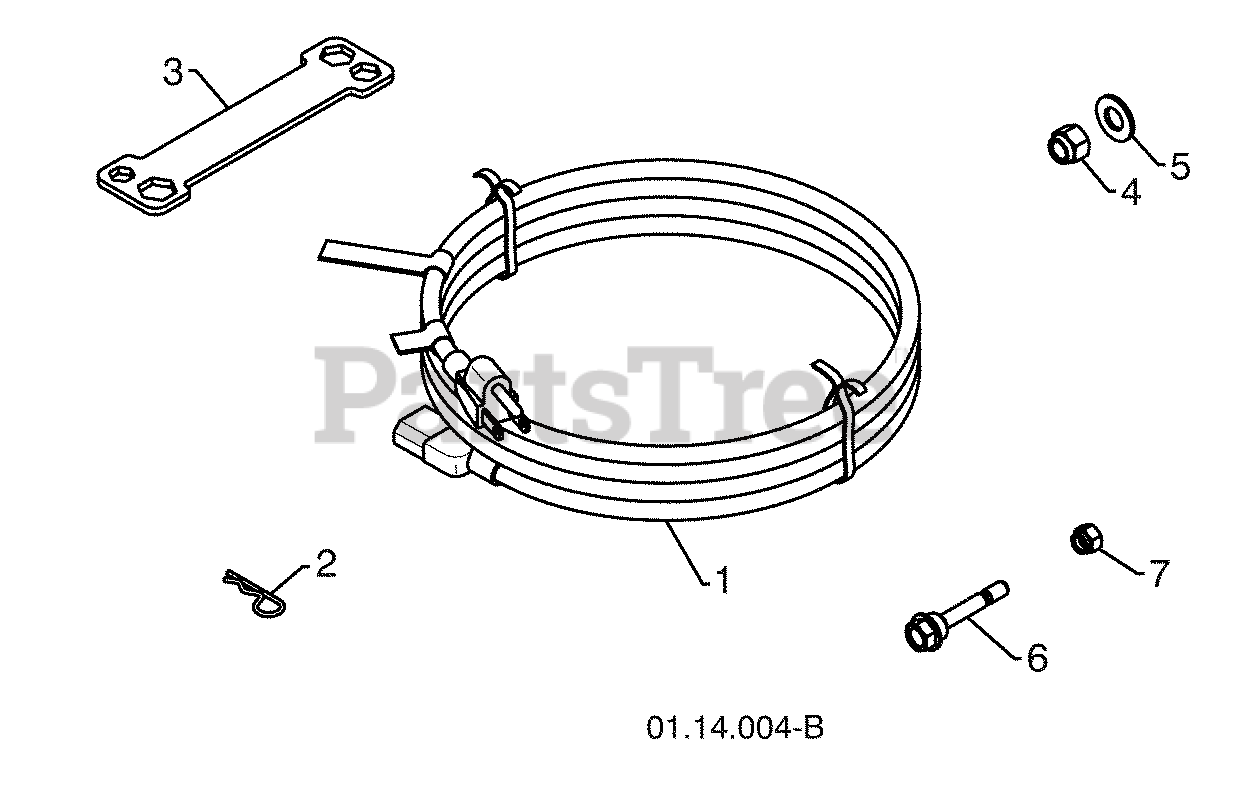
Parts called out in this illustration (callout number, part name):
1	POWER CORD
2	RETAINER PIN
4	LOCKNUT 3/8-16
5	WASHER 3/8
6	SHEAR BOLT 1/4-20 X 1-3/4
7	LOCKNUT 1/4-20
